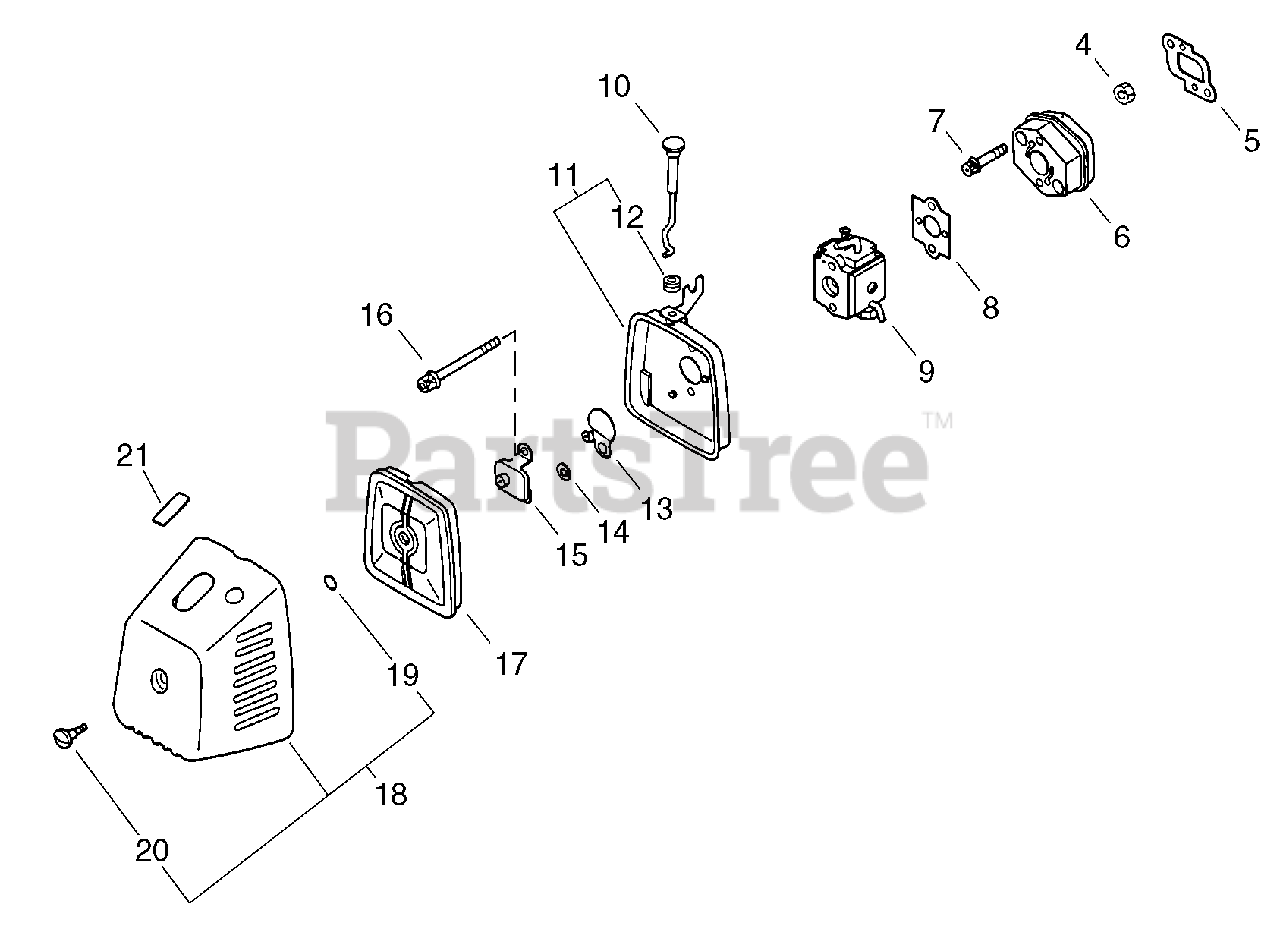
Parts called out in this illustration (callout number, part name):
5	GASKET, INTAKE
6	INSULATOR, INTAKE
7	SCREW - 5X25
8	GASKET, INTAKE
9	CARBURETOR WT-120B
10	ROD, CHOKE
11	AIR FILTER CASE ASSY
13	SHUTTER, CHOKE
14	WASHER - 5
15	PLATE, PREVENT
16	SCREW - 5X57
17	FILTER, AIR
18	AIR FILTER COVER ASSY
19	O-RING - 4
21	LABEL - CHOKE
